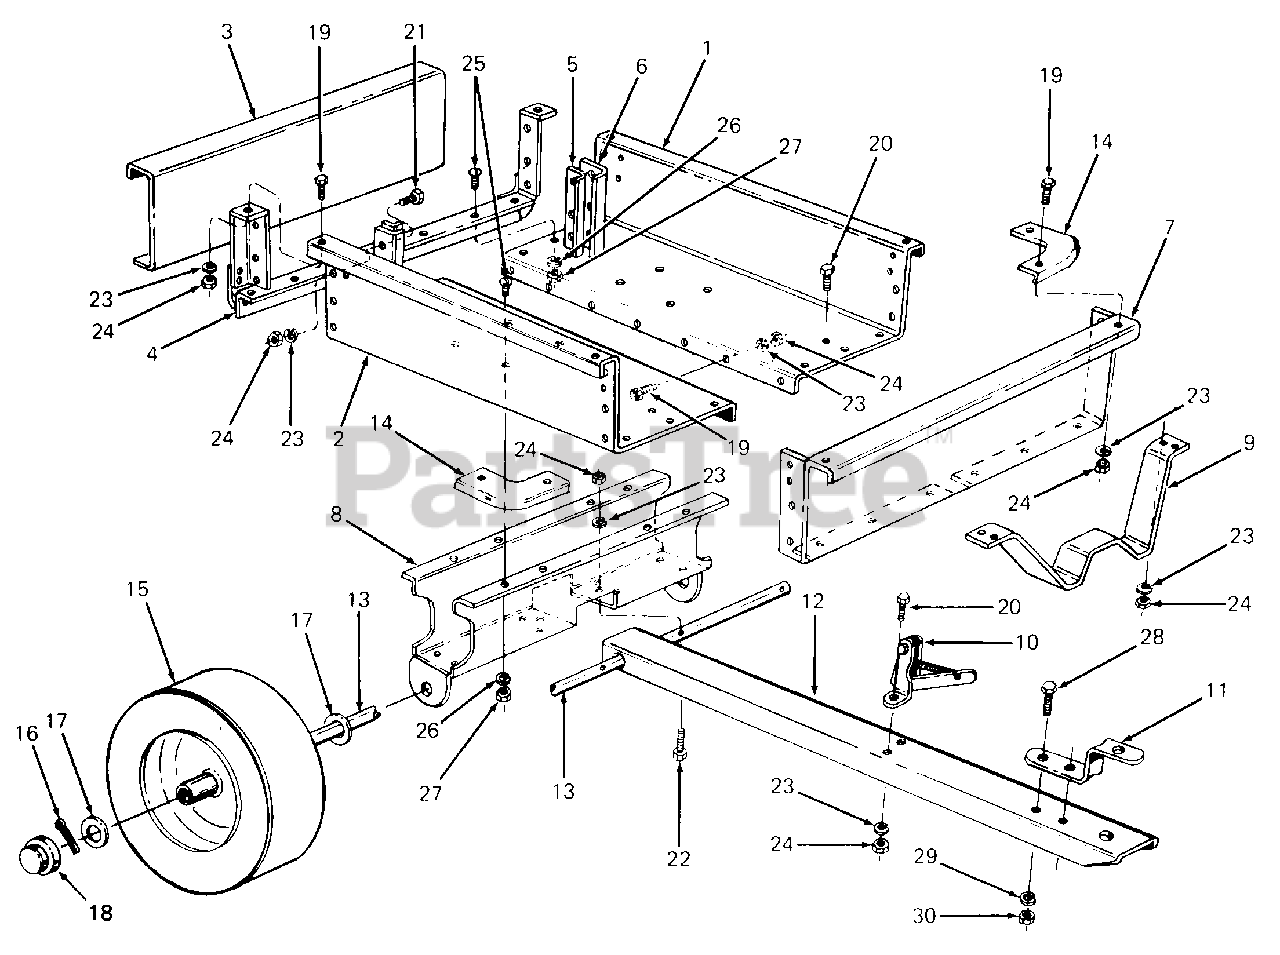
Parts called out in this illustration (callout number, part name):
1	Cart Body LH
2	Cart Body RH
6	Guide, Tailgate - Outside
17	Washer, Flat, .781 x 1.59 x .065
18	Hub Cap
19	Screw, Hex Cap, 1/4-20 x .50 Lg
20	Screw, Hex Cap, 1/4-20 x .62 Lg
21	Screw, Hex Cap, 1/4-20 x .75 Lg
22	Screw, Hex Cap, 1/4-20 x 1.50 Lg
23	Washer, Lock, 1/4
24	Nut, Hex, 1/4-20
25	Screw, Truss Hd, 5/16-18 x .75 Lg
26	Washer, Lock, 5/16
27	Nut, Hex, 5/16-18
28	Screw, Hex Cap, 3/8-16 x 1.0 Lg GR 5
29	Washer, Lock, 3/8
30	Nut, Hex, 3/8-16
